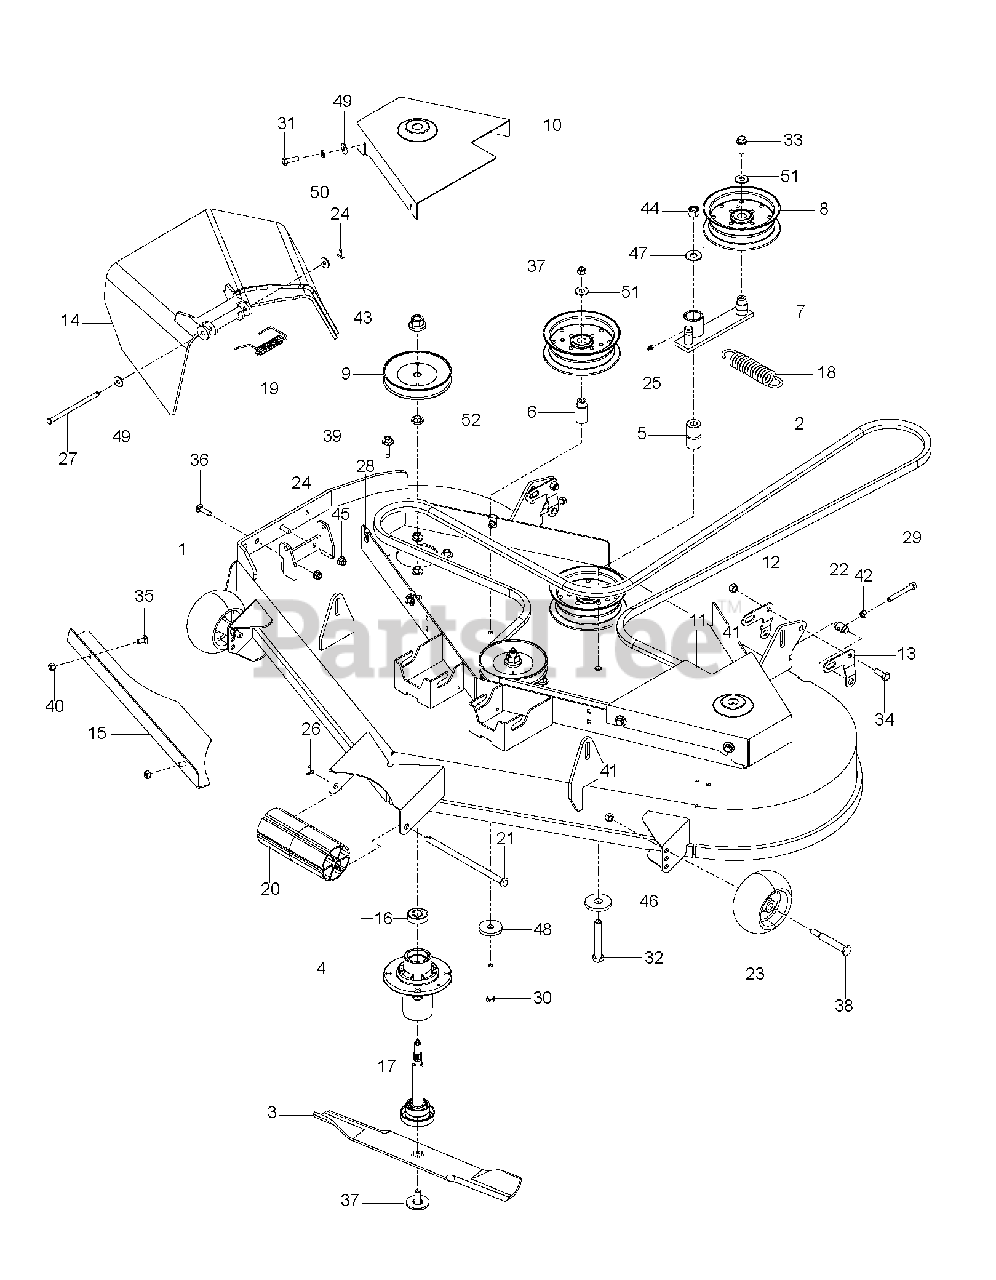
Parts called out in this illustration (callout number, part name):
1	DECK MZT 52 W/SFTY DECALS.ORNG
3	BLADE, 18"
4	MANDREL.DECK.ASSEMBLY
5	PIVOT BUSHING
6	IDLER BUSHING
8	PULLEY, IDLER
9	PULLEY MANDREL
10	BELT SHIELD, RIGHT 52, ORG
11	BELT SHIELD, LEFT 52, ORG
12	BRACKET.RT.PNT.MS431
13	BRACKET.LH.PNT.MS431
14	DISCHARGE CHUTE 52"
15	CONFINEMENT PLATE, 52"
17	SHAFT ASM MANDREL
19	SPRING - TORSION
20	NOSE ROLLER 48"
21	ROD.ROLLER.NOSE.NARROW.48"
22	TRUNION, PITCH
23	GAUGE WHEEL
24	BRACKET MZ CHUTE
25	ZERK
26	RP_COTTER PIN 1/8 X 3/4
27	PIN-CLEVIS 5/16 DIA X 5.19 ZD
28	U-CLIP 5/16-18 NUT RETAINER
29	HCS 5/16-18 X 2 1/2 TPBLT
30	BOLT.HEX.FIN.3/8-16 X 3.GR5
31	BOLT.FIN.HEX.5/16-18UNC X 1.00
32	HCS 1/2C X 3 1/4
33	4CS 3/8C X 1 SERRATED HEAD
34	HCS 3/8-16X1.GRD.5.ZD
35	BOLT
37	BLADE BOLT ASSY-7/16" TB REPL
38	BOLT, SHOULDER
39	BOLT.HEX.WASHR.HED.313-18X1.19
40	NUT.71038.31-18.HEX.NYLOCK
41	NUT 3/8-16 NYLOC
42	NUT 5/16C HEX
43	LOCKNUT - 9/16
44	RP NUT 1/2-13 HEX NYLOC ZD
45	5/16-18 NYLOC FLANGE NUT
46	WASHER, SUPPORT
47	WASHER 1/2 FLAT
48	SPINDLE WASHER
49	WASHER
50	WASH.5/16.SLW.ZD
51	WASHER 3/8 FLAT
52	WASHER-SPACER
